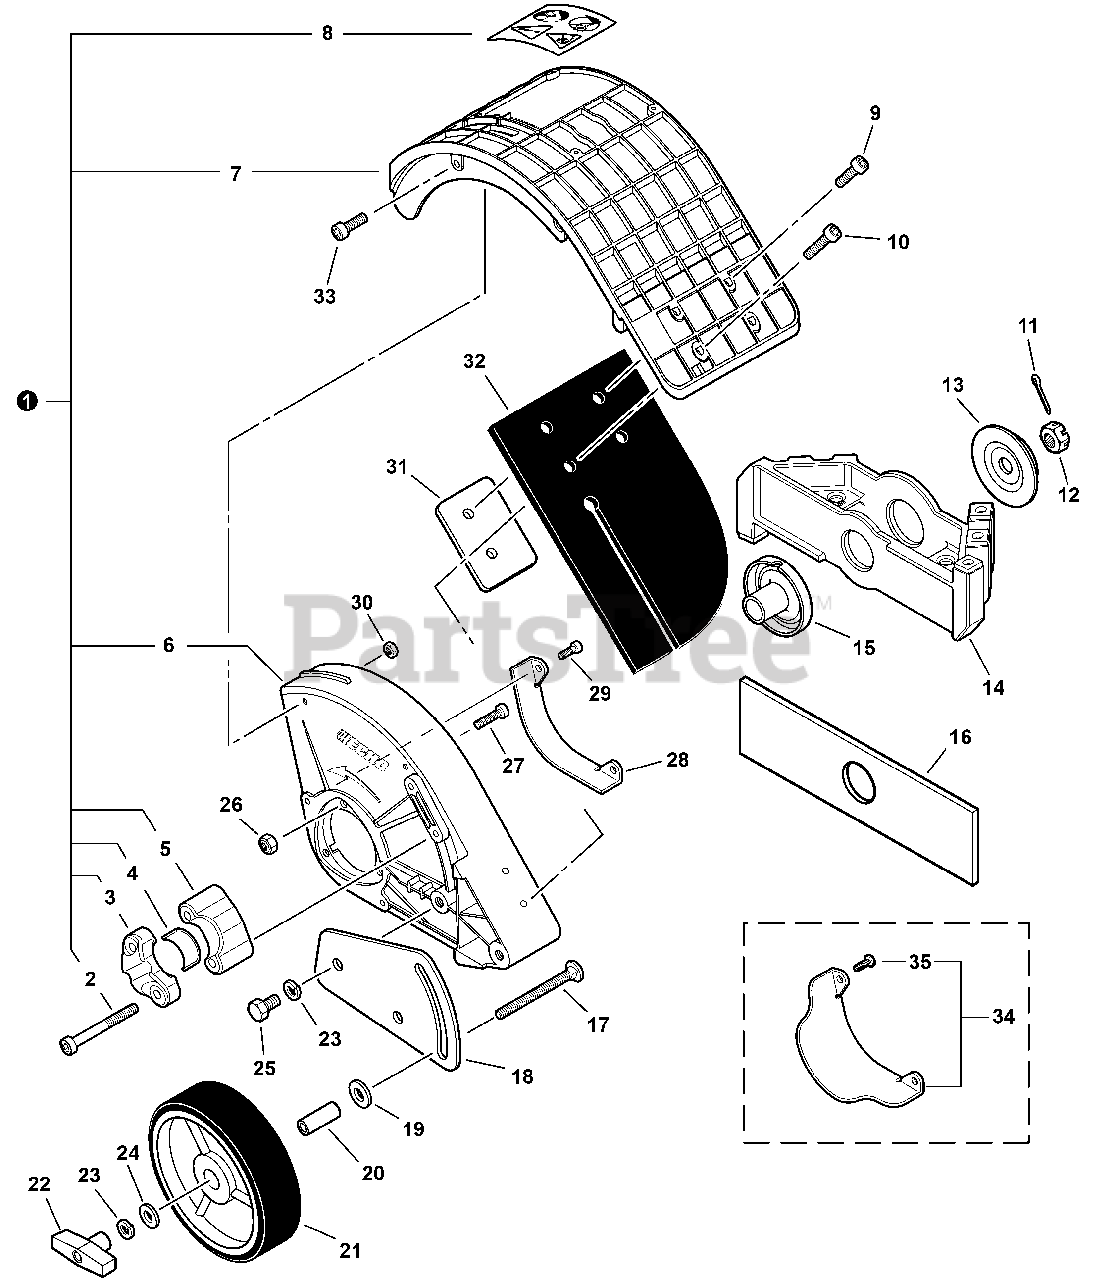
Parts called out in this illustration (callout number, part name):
1	BED REDEFINER KIT
2	SCREW - 6×35
3	BRACKET - OUTER
4	PAD, FOAM
5	BRACKET - INNER
6	SHIELD, BLADE
7	SHIELD, DEBRIS
8	LABEL, CAUTION
9	BOLT, TORX 4×12
10	BOLT, TORX 4×16
11	PIN, COTTER 2×22
12	NUT 10×1.25 LH
13	PLATE, ADAPTOR - LOWER
14	BLADE, REDEFINER
15	PLATE, ADAPTOR - UPPER
16	BLADE - 2 PK
17	BOLT 5/16"-18×2-1/2"
18	BRACKET, WHEEL
19	WASHER, SPRING 10
20	COLLAR 12
21	WHEEL
22	KNOB, FASTENER
23	WASHER, SPRING 8
25	BOLT 8×14
26	NUT, LOCK M5
27	BOLT, TORX 5×20
28	GUARD, SHIELD
29	BOLT, TORX 4×12
30	NUT, LOCK 4
31	PLATE, FLAP
32	FLAP, DEBRIS
33	BOLT, TORX 4×12
34	GUARD KIT, SHIELD
35	SCREW 4×12
